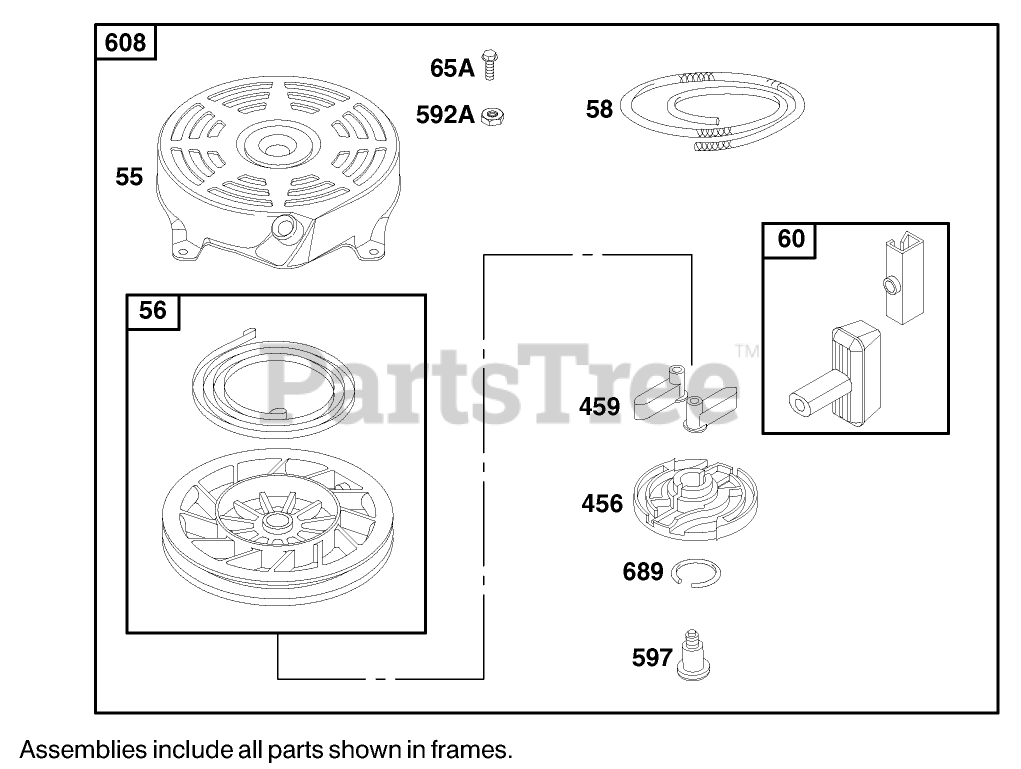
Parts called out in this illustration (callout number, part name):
56	PULLEY-STARTER, REWIND
58	ROPE-STARTER
65A	SCREW-HH
456	RETAINER-STARTER, REWIND
459	PAWL-STARTER
592A	NUT-HEX
608	REWIND ASM
689	SPRING-TORSION
